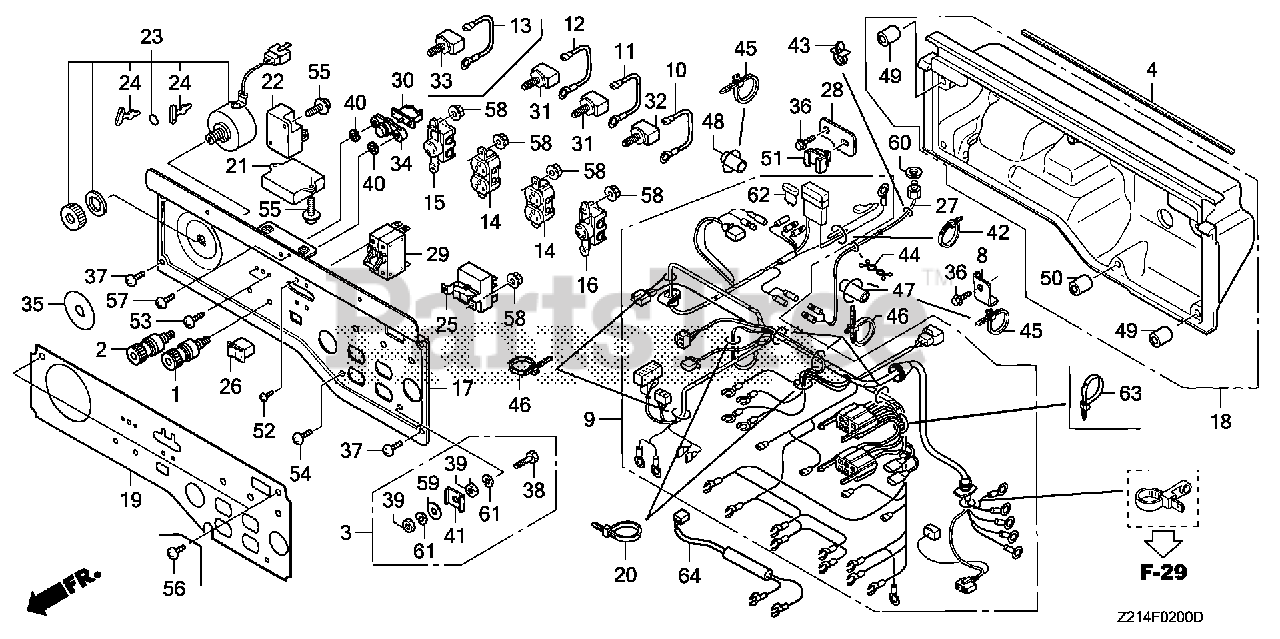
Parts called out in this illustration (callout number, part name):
1	TERMINAL, D.C. OUT (+)
2	TERMINAL, D.C. OUTPUT (-)
3	TERMINAL SET, GROUND
4	RUBBER, CONTROL
8	BRACKET, WIRE HARNESS CLIP (A)
9	WIRE HARNESS ASSY., CONTROL
10	WIRE, TERMINAL (A)
11	WIRE, TERMINAL (B)
12	WIRE, TERMINAL (C)
14	RECEPTACLE ASSY. (125V-20A) (MATSUSHITA)
14	RECEPTACLE (20A/125V) (CONFIRM RECEPTACLE AS NON-GCFI. IF GCFI, TRY #42.)
15	RECEPTACLE (30A-125V)
15	RECEPTACLE (3-PRONG) (30A/125V)
16	RECEPTACLE (20A-125/250V)
16	RECEPTACLE (20A-125/250V) (MATSUSHITA) (NOT AVAILABLE)
17	PANEL, CONTROL *NH105* (MAT BLACK)
18	CASE, CONTROL PANEL *R280* (POWER RED)
19	MARK, PANEL
20	TIE, CABLE (C)
21	CONTROL UNIT, ENGINE
22	CONTROL UNIT, IDLE
23	SWITCH ASSY., COMBINATION
24	KEY
25	SWITCH ASSY., VOLT CHANGE
26	SWITCH ASSY., IDLE CONTROL
27	SENSOR ASSY., TEMPERATURE
28	BRACKET, FUSE
29	BREAKER, CIRCUIT (15A)
30	PROTECTOR, CIRCUIT (15A)
31	PROTECTOR, CIRCUIT (20A)
32	PROTECTOR, CIRCUIT (20A)
34	LENS ASSY., PROTECTOR
35	MARK, ENGINE SWITCH
36	BOLT, FLANGE (6X12) (CT200)
37	SCREW, TRUSS (6X18)
38	BOLT, HEX. (6X28)
39	NUT, HEX. (6MM)
40	WASHER (4MM)
41	RETAINER (6MM)
42	BAND, WIRE (95MM)
43	CLIP, WIRE HARNESS (6MM) (WHITE)
44	CLIP, WIRE HARNESS
45	STRAP, CABLE (105MM) *NH1* (Honda Code 1685536). (BLACK)
46	TIE, CABLE (NATURAL 225X5.0)
47	TUBE, CORD
48	TUBE (22X60)
49	COLLAR, CONTROL CASE
50	COLLAR, CONTROL CASE
51	CLIP, CONNECTOR HOLDER (BROWN)
52	SCREW, PAN (3X5) (NOT AVAILABLE)
53	SCREW, PAN (3X16)
54	SCREW, PAN (5X18)
55	SCREW-WASHER (5X14)
57	SCREW, TAPPING (4X16) (NOT AVAILABLE)
58	NUT, FLANGE (4MM)
59	WASHER, PLAIN (6MM)
60	WASHER, PLAIN (8MM)
61	WASHER, SPRING (6MM)
62	FUSE, BLADE (10A)
